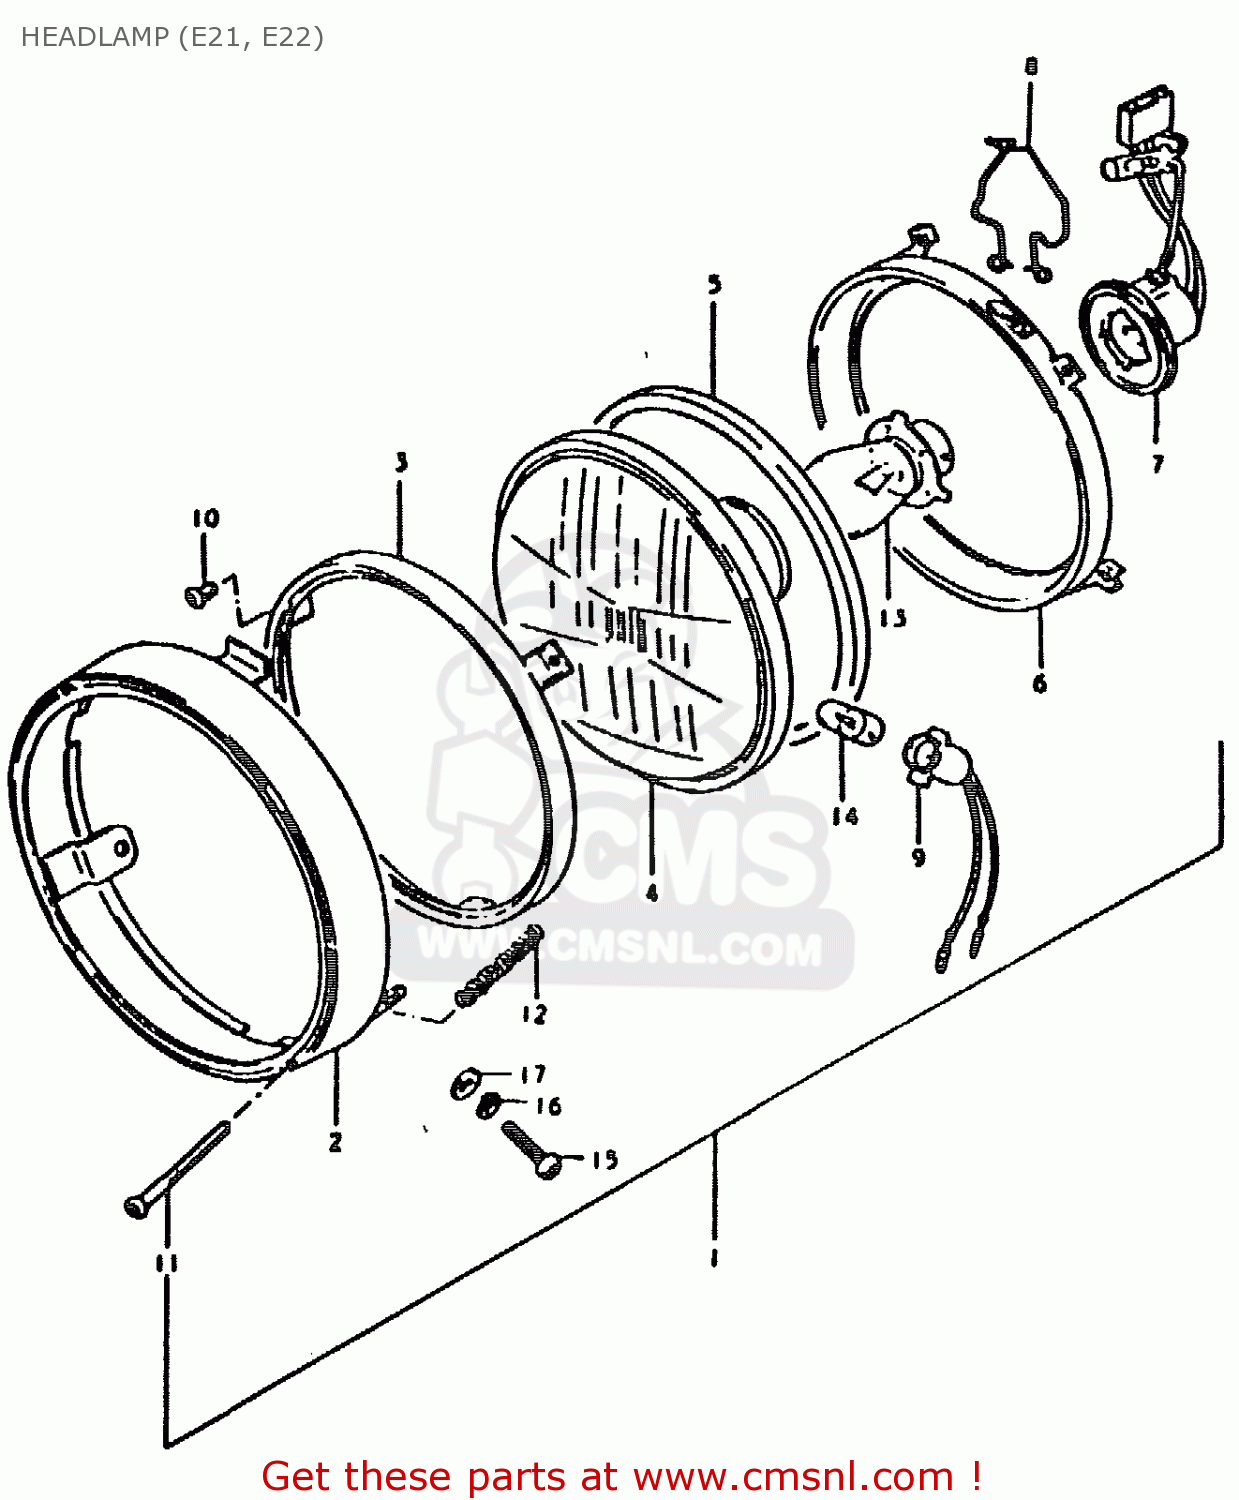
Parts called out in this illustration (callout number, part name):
1	HEADLAMP ASSY
2	RIM
3	RING
4	UNIT
5	GASKET
6	RING, MOUNTING
7	SOCKET
8	CLAMP,HEADLAMP
9	SOCKET
10	SCREW
11	SCREW,HEADLAMP ADJUST
12	SPRING,ADJUSTING
13	BULB (6V,25/25W)
14	BULB (6V,4W)
15	SCREW
16	LOCK WASHER
17	WASHER
